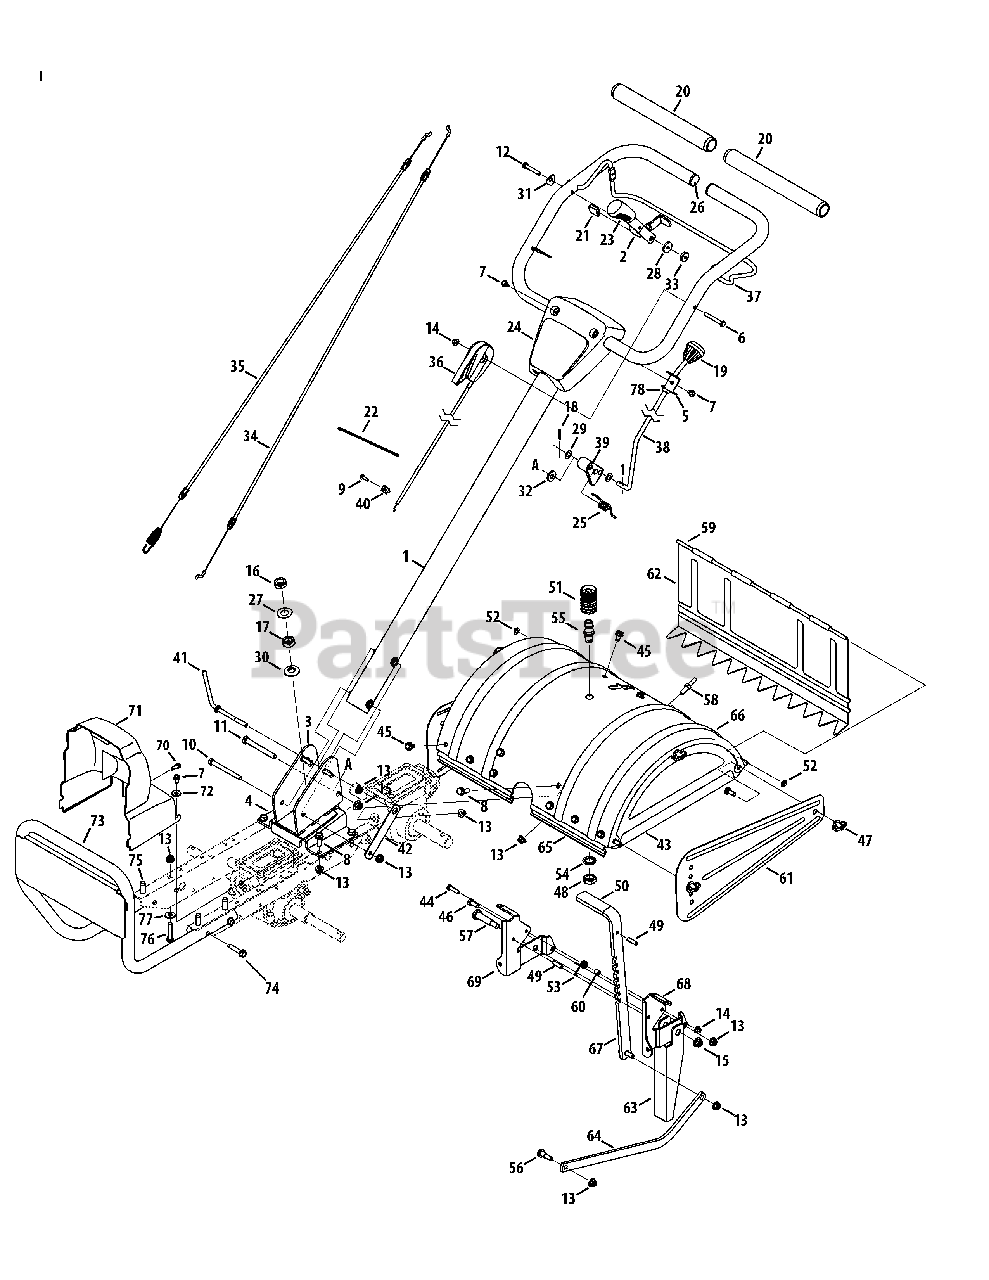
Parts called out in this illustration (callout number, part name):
1	Upper Handle Assembly
2	Reverse Handle Assembly
3	Handle Bracket Assembly
4	Handle Bracket Assembly Base
5	Control Rod Support Bracket
6	Hex Head Screw, 1/4-20 x 2.0
7	Self-Tapping Screw, 1/4-20 x 1/2
8	Hex Head Screw, 5/16-18 x .875
9	Hex Head Washer, #10-32 x .75
10	Hex Head Screw, 5/16-18 x 3.25
11	Hex Head Screw, 3/8-16 x 3.25
12	Hex Head Screw, 1/4-20 x 1.62
13	Nylon Hex Lock Nut, 5/16-18
14	Nylon Hex Lock Nut, 1/4-20
15	Flange Lock Nut, 3/8-16
16	Hex Jam Nut, 5/8-18
17	Jam Nut, 5/8-18
18	Cotter Pin 3/32" Dia. x .75"
19	Knob, Shift
20	Foam Handle Grip
21	Reverse Handle Grip
22	Cable Tie
23	Handle Select
24	Handle Cover
25	Spring Handle Adj.
26	Plug End
27	Flat Washer, .656 x 1.25 x .02
28	Flat Washer, .265 x .938 x .120
29	Washer, Thrust, .375 x .7 x .03
30	Bell Washer, .63 x 1.25 x .18
31	Saddle Washer, .320 x .930 x .060
32	Flat Washer, .406 x .875 x .105
33	Spacer, .375 x .165
34	Reverse Cable
35	Forward Cable
36	Throttle Cable
37	Clutch Bail
38	Pivot Control Rod
39	Handle Link
40	Casing Clamp
41	Handle Crank
42	Retainer Nut Bracket
43	End Cover Assembly
44	Hex Head Screw, 1/4-20 x 1
45	Hex Head Screw, 5/16-18 x .625
46	Hex Head Screw, 5/16-18 x .75
47	Wing Nut, 5/16-18
48	Hex Nut, M-16 x 1.5
49	Spirol Pin
50	Handle Grip
51	Water Nozzle Adapter
52	Cap Nut, 1/4 Rod
53	Torsion Spring
54	Lock Washer, 5/8
55	Deck Water Nozzle
56	Shoulder Screw, .405 x .435 5/16-18
57	Shoulder Screw, .498 x 1.635
58	Stop Screw
59	Tiller Flap Rod
62	Rear Tine Shield
63	Reverse Stop Arm
65	Tine Shield Mounting Bracket
67	Adjustable Depth Bar
68	Tail Bracket, LH
69	Tail Bracket, RH
70	Self Tapping Screw, 1/4-14 x .625
71	Belt Cover
72	Flat Washer, .28 x .74 x .063
74	Hex Head Screw, 5/16-18 x 1.50
75	SEMS Screw, 3/8-16
76	Hex Head Screw, 5/16-18 x 1.50
77	Belleville Washer, .331 x .827 x .098
78	Control Rod Bushing
